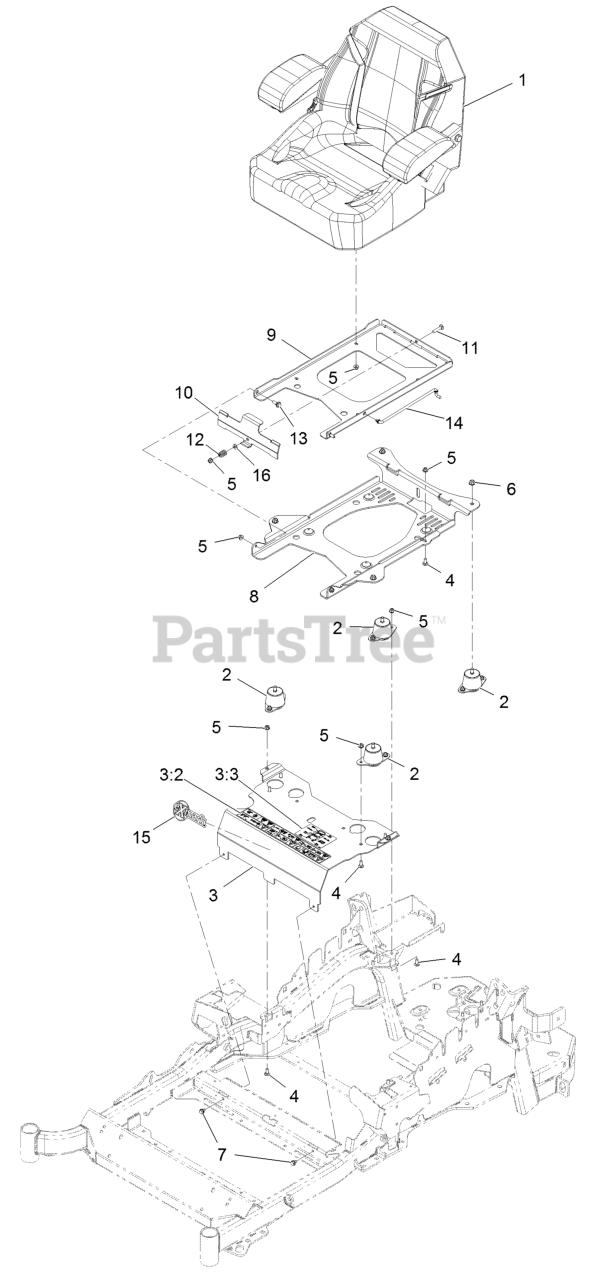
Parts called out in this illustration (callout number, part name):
2	ISOLATOR-SEAT
3	MOUNT-SEAT
3:2	DECAL-CONSOLE
3:3	DECAL-SERVICE AID
4	SCREW-CARR
5	NUT-HF, NI
6	NUT-HF, NI
8	PLATE-TILT, SEAT SUPPORT
9	PLATE-FRAME, SEAT
10	PLATE-LATCH, SEAT
11	BOLT-CARR
12	SPRING-COMPRESSION
13	SCREW-SHOULDER
14	ROD-PROP
16	WASHER-PLAIN
